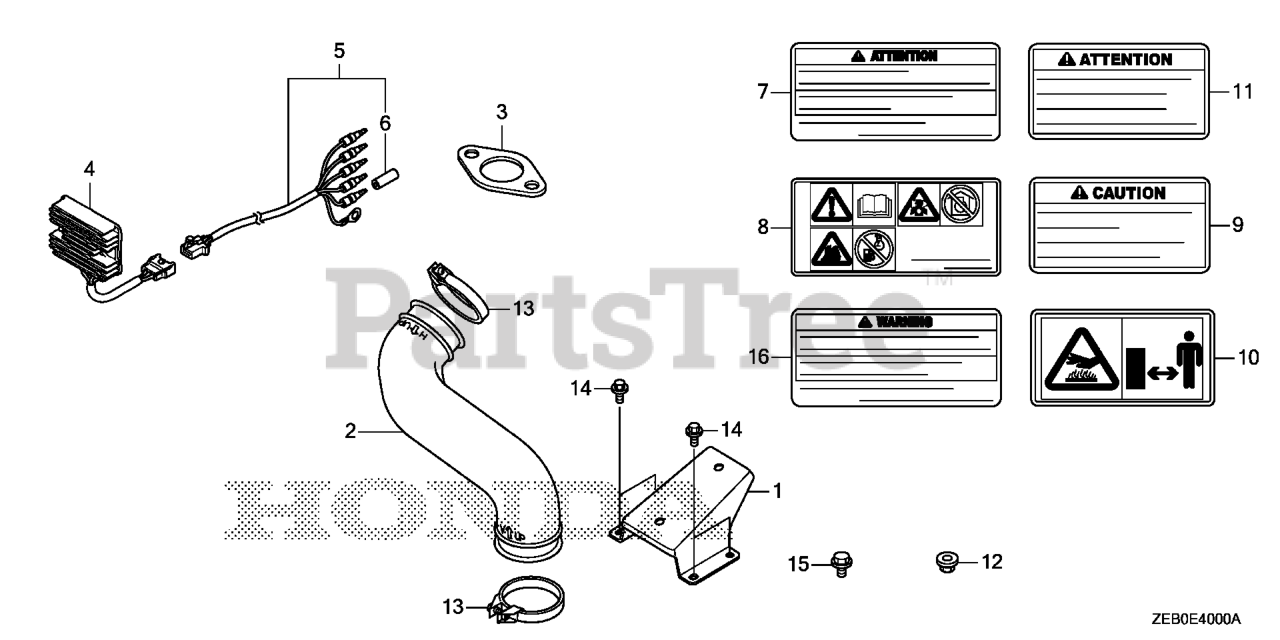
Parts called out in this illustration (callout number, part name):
1	STAY, SUB-AIR CLEANER
2	TUBE, AIR CLEANER CONNECTING
3	GASKET, EX. PIPE
4	RECTIFIER ASSY., REGULATOR (17A)
5	SUB-WIRE HARNESS ASSY.
6	PLUG, CONNECTOR (OUTER) (ENGINE NO.)
7	MARK, OPERATOR CAUTION (FRENCH)
8	MARK, OPERATOR CAUTION (PICTOGRAPH)
9	MARK, EX. CAUTION (ENGLISH)
10	MARK, EX. CAUTION (PICTOGRAPH)
11	MARK, EX. CAUTION (FRENCH)
12	NUT, FLANGE (8MM)
13	BAND, AIR CLEANER CONNECTING TUBE (58)
14	BOLT, FLANGE (6X12) Use up to Engine SN 1543277.
15	BOLT, FLANGE (8X14)
